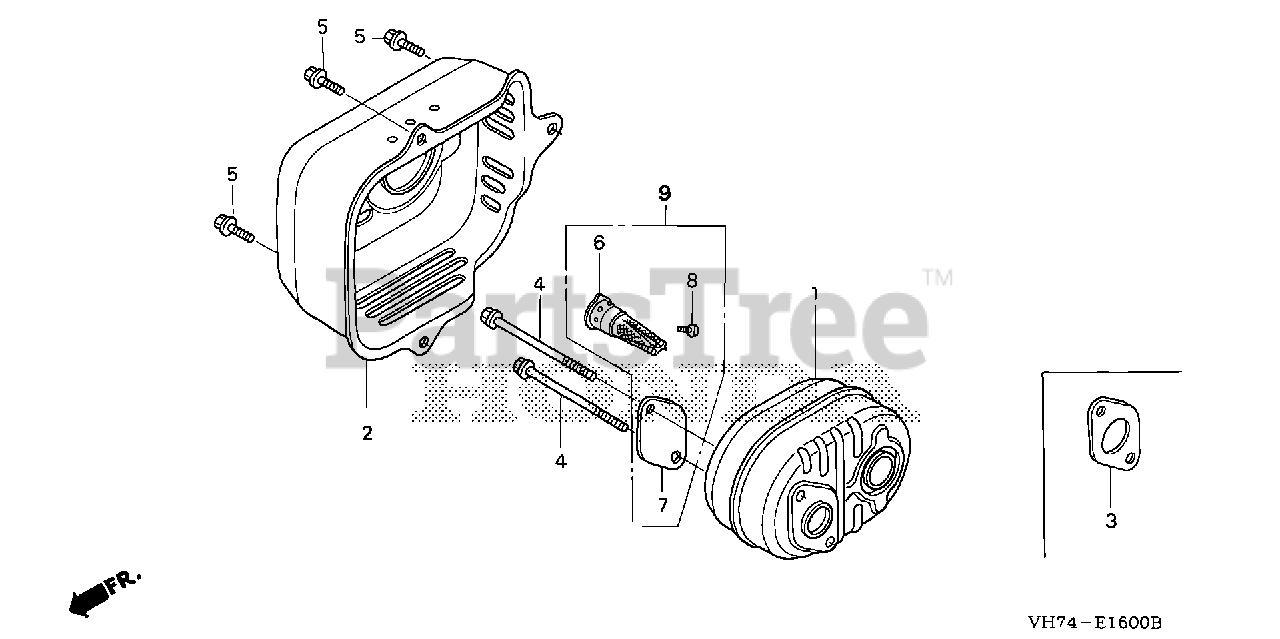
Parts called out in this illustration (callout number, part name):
1	MUFFLER
2	PROTECTOR, MUFFLER
3	GASKET, MUFFLER
4	BOLT, FLANGE (6X79) (CT200)
5	BOLT, FLANGE (6X12) (CT200)
6	ARRESTER, SPARK
7	PLATE, ARRESTER NUMBER
8	SCREW, TAPPING (4X6)
9	ARRESTER KIT, SPARK
